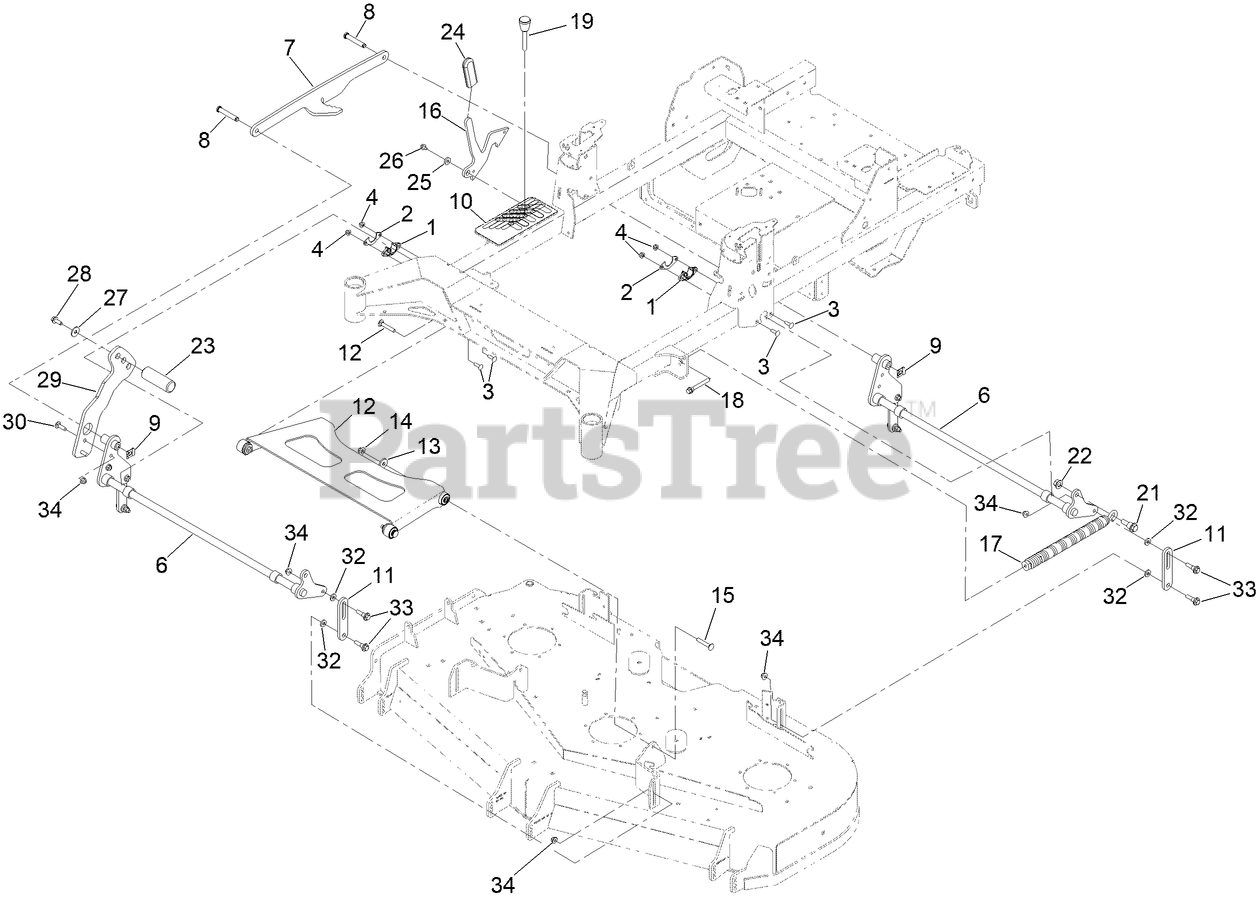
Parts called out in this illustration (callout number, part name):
1	BEARING-FLANGE
2	GUSSET-LIFT, DECK
3	SCREW-CARR
4	NUT-HF, NI
6	DECK LIFT SHAFT ASM [BLACK]
7	LINK-LIFT
8	PIN-CLEVIS
9	CLIP-PIN
10	DECAL-HOC
11	LINK-LIFT, DECK
12	ASM-DECK STRUT W/ BUSHINGS
13	WASHER
14	NUT-FLANGE, NI
15	SCREW-CARR
16	PLATE-TRANSPORT LOCK
17	SPRING-EXTENSION
18	BOLT-SHOULDER
19	PIN-HOC
21	SCREW-SHOULDER, HHF
22	NUT-LOCK
23	PEDAL-FOOT LIFT
24	GRIP-LEVER
25	SPACER
26	SCREW
27	WASHER
28	SCREW-HHF
29	ARM-DECK LIFT [BLACK]
30	BOLT-CARR
32	SPACER
33	BOLT-SHOULDER
34	NUT-HF, NI
